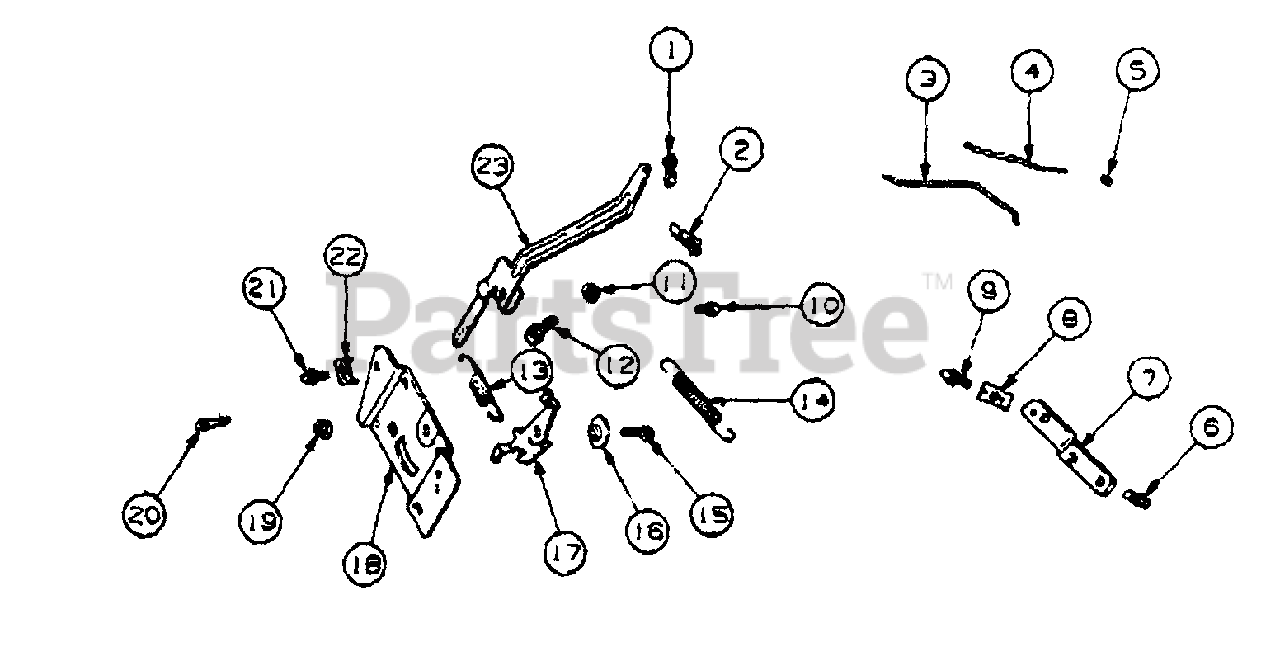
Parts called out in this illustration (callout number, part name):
1	Bushing, Throttle
2	Lever, Choke, Upper
3	Linkage, Choke, Upper
4	Linkage, Throttle
5	Bushing, Linkage
6	Screw, Bracket, M5 x 0.8 x 10
7	Bracket, Choke Mount
8	Clamp, Cable
9	Screw, Clamp, M5 x 0.8 x 16
10	Screw, M5 x 0.8 x 10
11	Nut, M6 x 1.0
12	Screw, Gov Arm, M6 x 1 x 25
13	Spring, Governor
14	Spring, Linkage
15	Screw, Throttle Cntrl, M5 x 0.8 x 16
16	Spacer, Throttle Control
17	Lever, Throttle Control
18	Plate, Control
19	Nut, Hex, M5 x .8
20	Screw, Control Plate, M6 x 1 x 16
21	Screw, Cable Clamp, M5 x 0.8 x 16
22	Clamp, Cable
23	Lever, Governor
